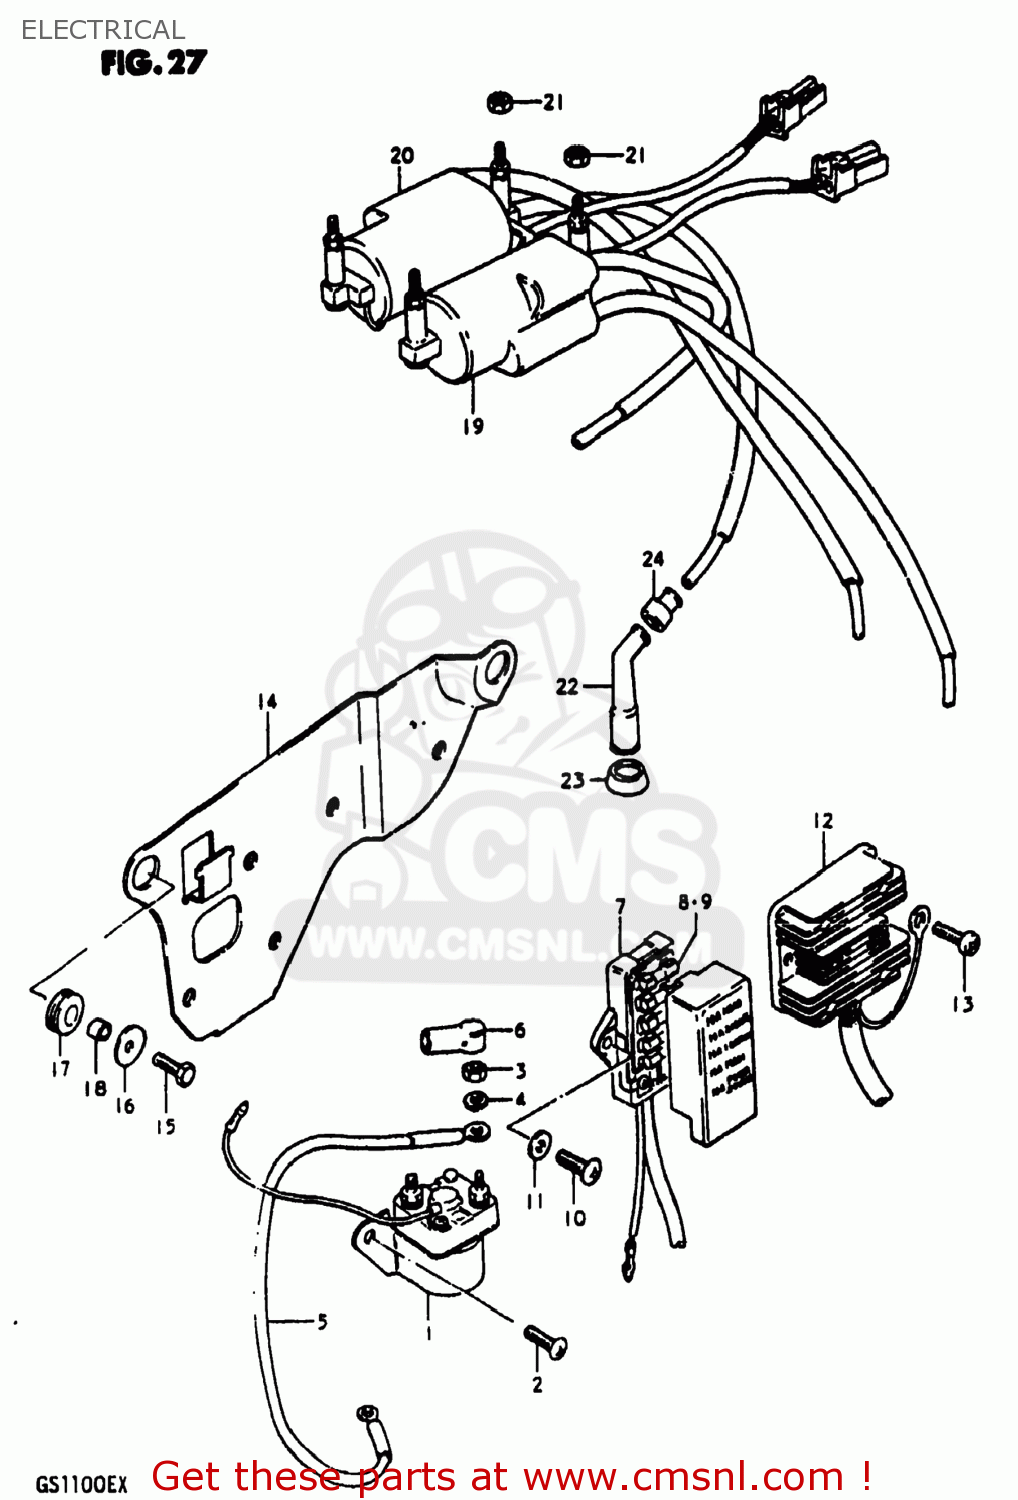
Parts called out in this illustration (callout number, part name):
1	RELAY ASSY,STARTING MOTOR
2	SCREW
3	NUT 6MM
4	LOCK WASHER
5	WIRE,STARTER MOTOR LEAD
6	CAP,STARTER RELAY
7	BOX ASSEMBLY,FUSE
8	FUSE(10A)
9	FUSE(15A)
10	SCREW
11	WASHER
12	RECTIFIER ASSEMBLY
13	SCREW 6X12
14	PLATE,ELECTRIC PARTS HOLDER
15	BOLT, UPPER
16	WASHER
17	CUSHION
18	SPACER (7X9X7)
19	COIL ASSEMBLY,IGNITION
20	COIL ASSEMBLY,IGNITION
21	NUT
22	CAP ASSY,SPARK PLUG
23	SEAL,SPARK PLUG
24	SEAL,SPARK PLU
